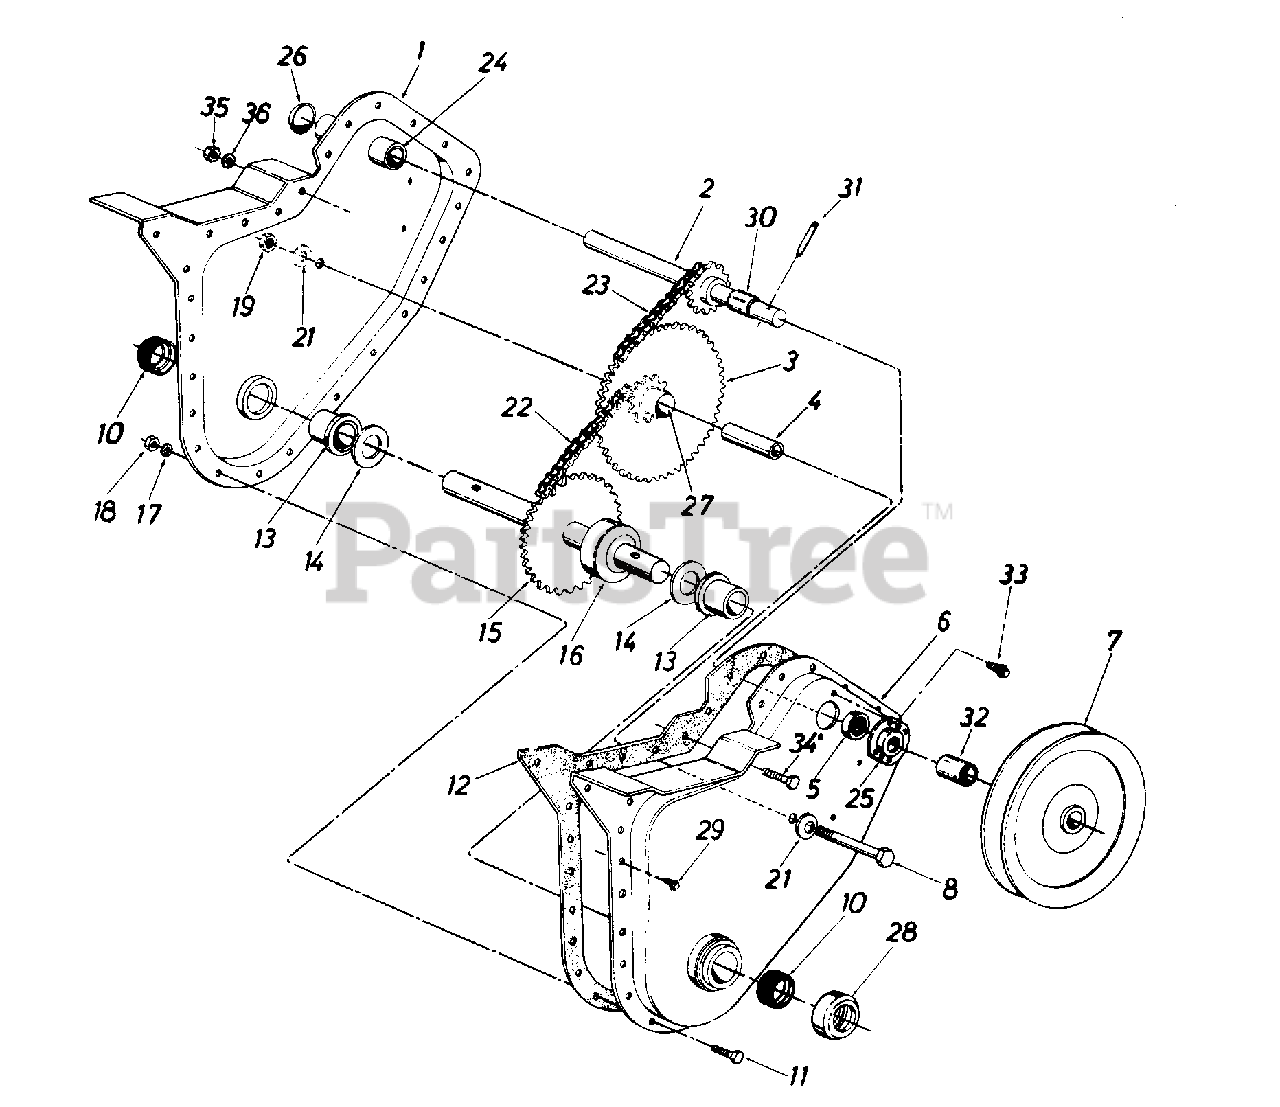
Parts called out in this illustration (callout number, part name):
1	Chain Case Ass'y. - R.H.
2	Input Shaft Ass'y.
3	Hub and Sprocket Ass'y.
4	Bearing Inner Race
5	Ball Bearing
8	Hex Bolt 3/8-24 x 2.5"
11	Hex Bolt 1/4-28 x .625"
12	Gasket
13	Flange Brg. .879" I.D.
14	Fl-Wash. .88" I.D. x 1.5"
15	Tine Shaft Ass'y.
16	Spacer 7/8" I.D.
17	L-Wash. 1/4" I.D.
18	Hex Nut 1/4-28 Thd.
19	Hex Ins. L-Nut 3/8-24 Thd.
21	Bell-Wash. .406" I.D.
22	Chain #420 1/2" Pitch 38 Links
23	Chain #35 .375" Pitch 50 Links
24	Bearing .62" I.D. x .813"
25	Bearing Housing
26	Expansion Plug 13/16" Dia.
27	Bearing
28	Dust Cap
29	Hex Wash. Hd. Self-Tap Scr. 1/4-20 x .50" Lg.
30	Spacer .63" I.D. x .77" O.D. x .38" Lg.
31	Spring Pin Spiral 1/4" Dia. x 1-1/2" Lg.
32	Spacer .647 x 1.25"
33	Hex Wash. Hd. Self-Tap Scr. 1/4-20 x .38" Lg.
34	Hex Bolt 5/16-18 x .75" Lg.
35	Hex Nut 5/16-18 Thd.
36	L-Wash. 5/16" I.D.
